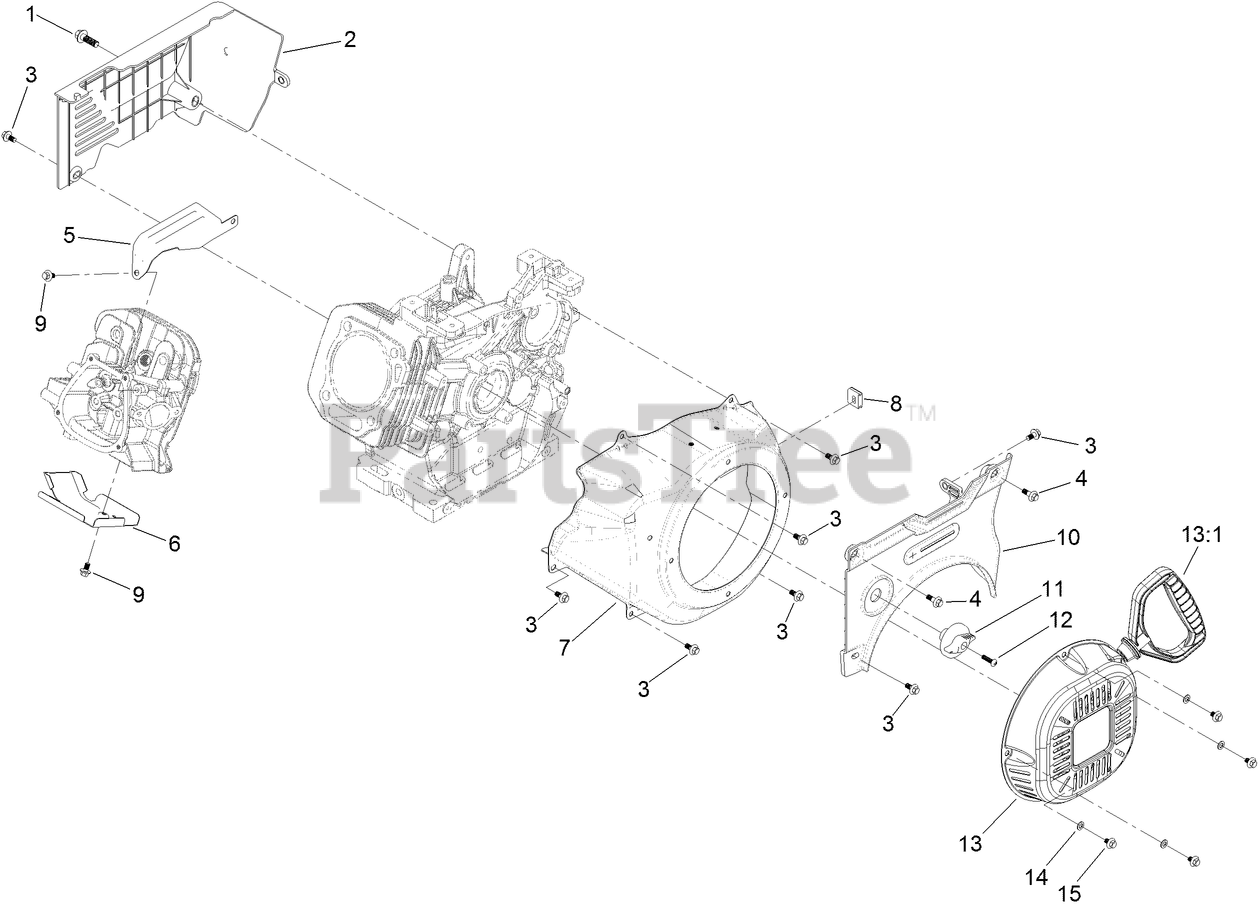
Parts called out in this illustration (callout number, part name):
1	SCREW-HHF
2	PANEL-REAR
3	SCREW-HHF
4	SCREW-HHF
5	SHROUD-HEAD, UPPER
6	SHROUD-HEAD, LOWER
7	SHROUD-RECOIL
8	GROMMET-RUBBER
9	SCREW-HHF
10	PANEL-CONTROL, FRONT
11	KNOB-VALVE, FUEL
12	SCREW-BHP
13	RECOIL ASM
13:1	HANDLE-RECOIL
14	WASHER-PLAIN
15	SCREW-HHF
